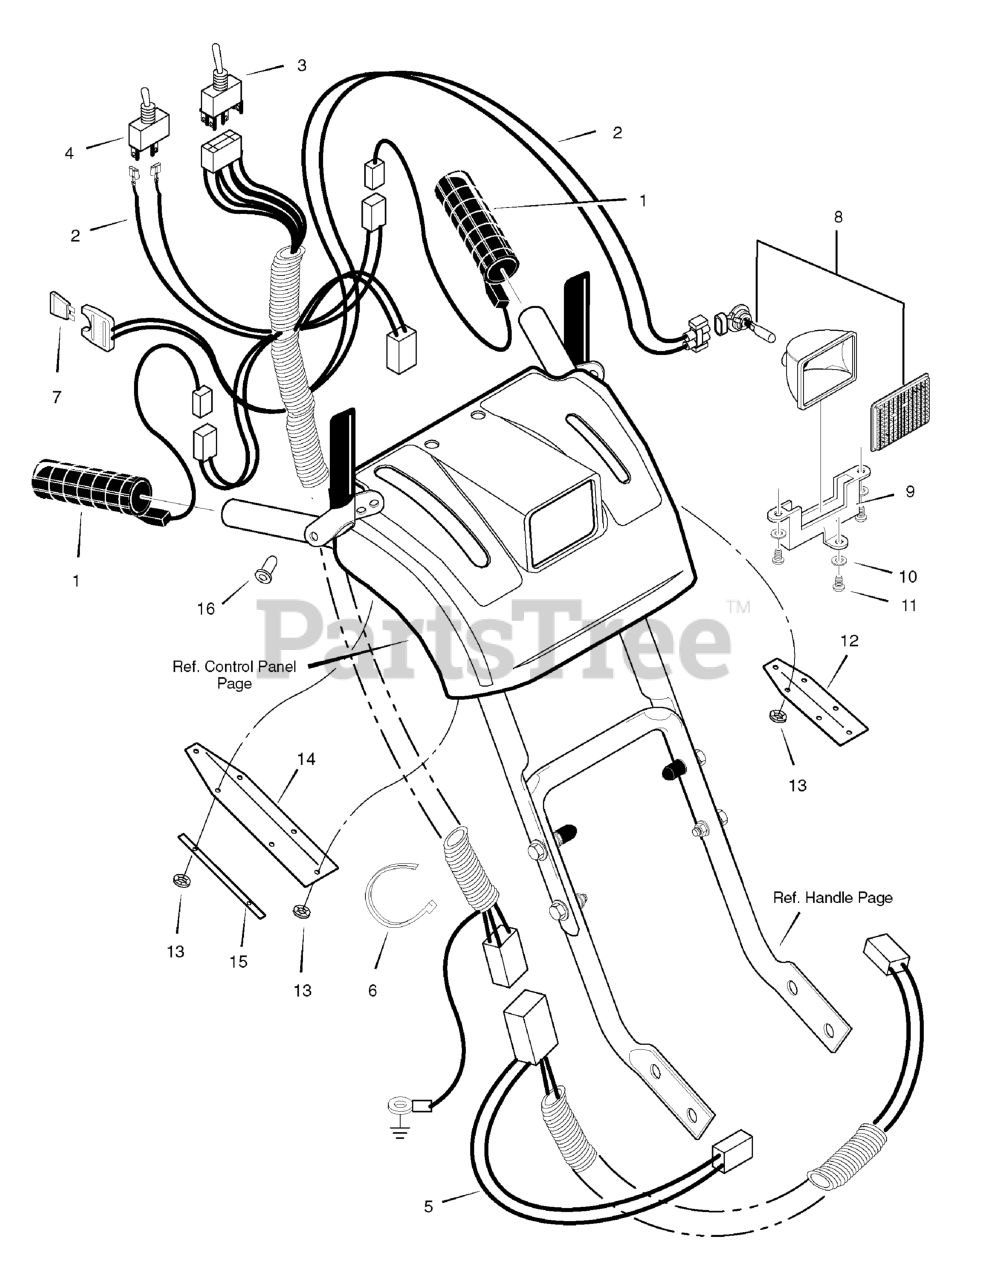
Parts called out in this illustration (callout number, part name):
1	GRIP, HEATED
2	WIRE HARNESS, UPPER
3	SWITCH, CHUTE ROTATION
4	SWITCH, HEATED GRIP
5	WIRE HARNESS, LOWER
6	TIE, CABLE
7	FUSE, 7.5 AMP AUTOMOTIVE
8	HEADLIGHT ASSEMBLY *
9	BRACKET
10	WASHER, FLAT
11	SCREW #8 X .50
13	NUT, PUSH
16	RIVET, 0.125 X 0.23
